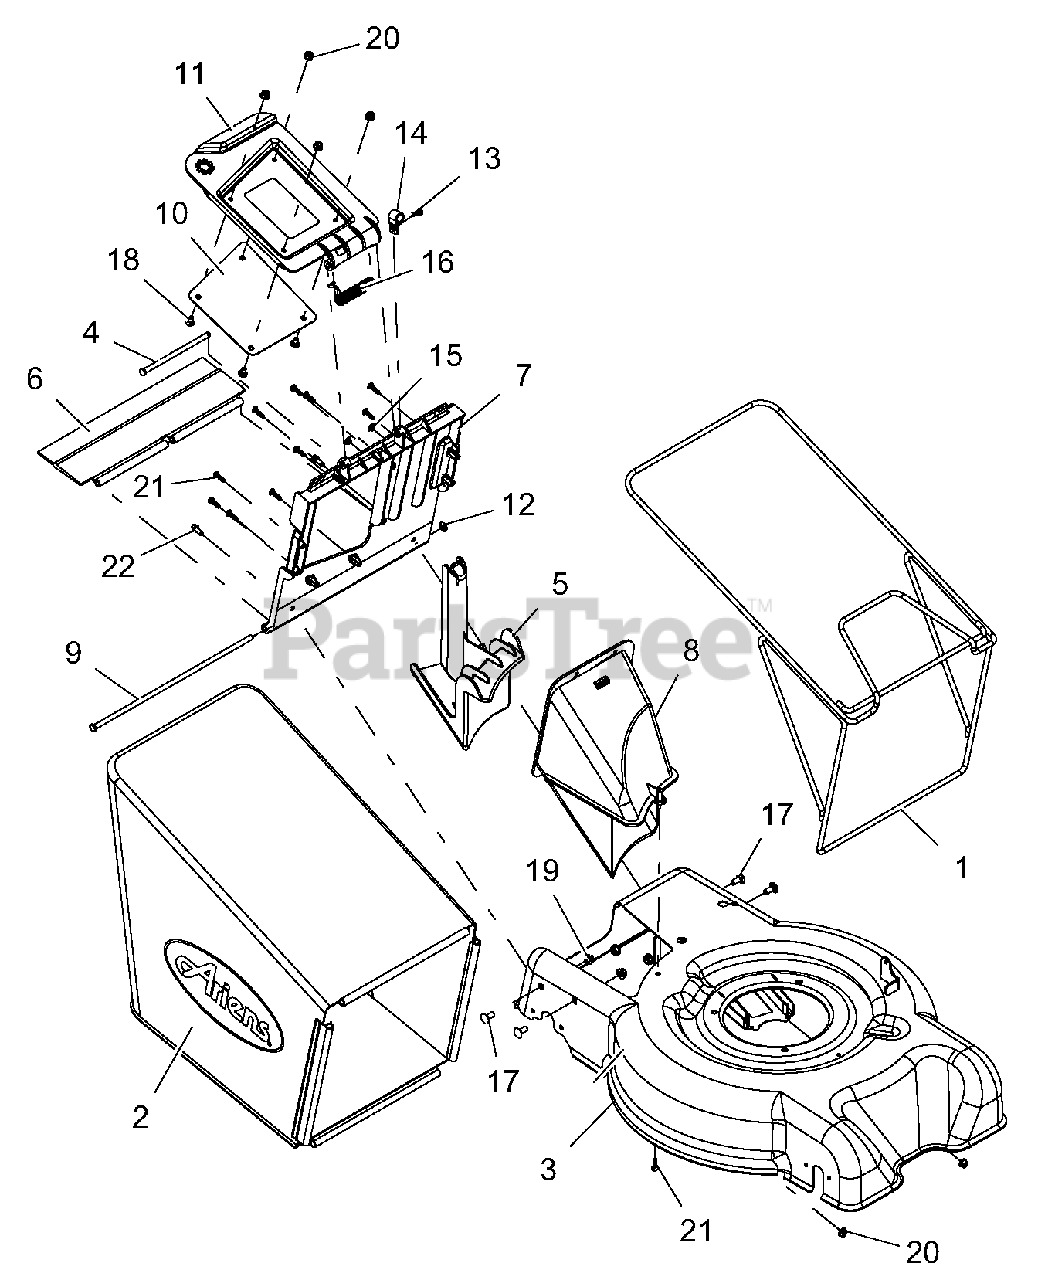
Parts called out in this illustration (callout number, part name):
1	FRAME, BAG
2	BAGGER, ARIENS LM
3	DECK W/ SAFETY DECAL
4	PIN, 5/16 X 5.80"
5	PLUG, MULCH
6	GUARD, REAR
7	HANGER, BAG
8	CHUTE, REAR DISCHARGE LM
9	ROD, REAR GUARD
10	PLATE, REAR DOOR
11	REAR DOOR W/ SAFETY DECAL
12	NUT-PUSH .312
13	PIN-HAIR INT .08X.18X1.18 YWZC
14	CLAMP, LM CABLE
15	PLUG,5/16 HOLE,.125 MATL PLSTC
16	SG-TORS .120X.68X3.09
17	@BLT-RDHDSQNK .31-18X.75 G5YZ
18	@BLT-RDHDSQNK .25-20X.50 G5YZ
19	@NUT-LK-TOP-FLG .31-18 YWZC
20	@NUT-LK-TOP-FLG .25-20 YWZC
21	SCR-TAP 12-14X.75PLSTITE @BLZC
22	@SCR-TAP .25-20X.62 HWH TR YWZ
